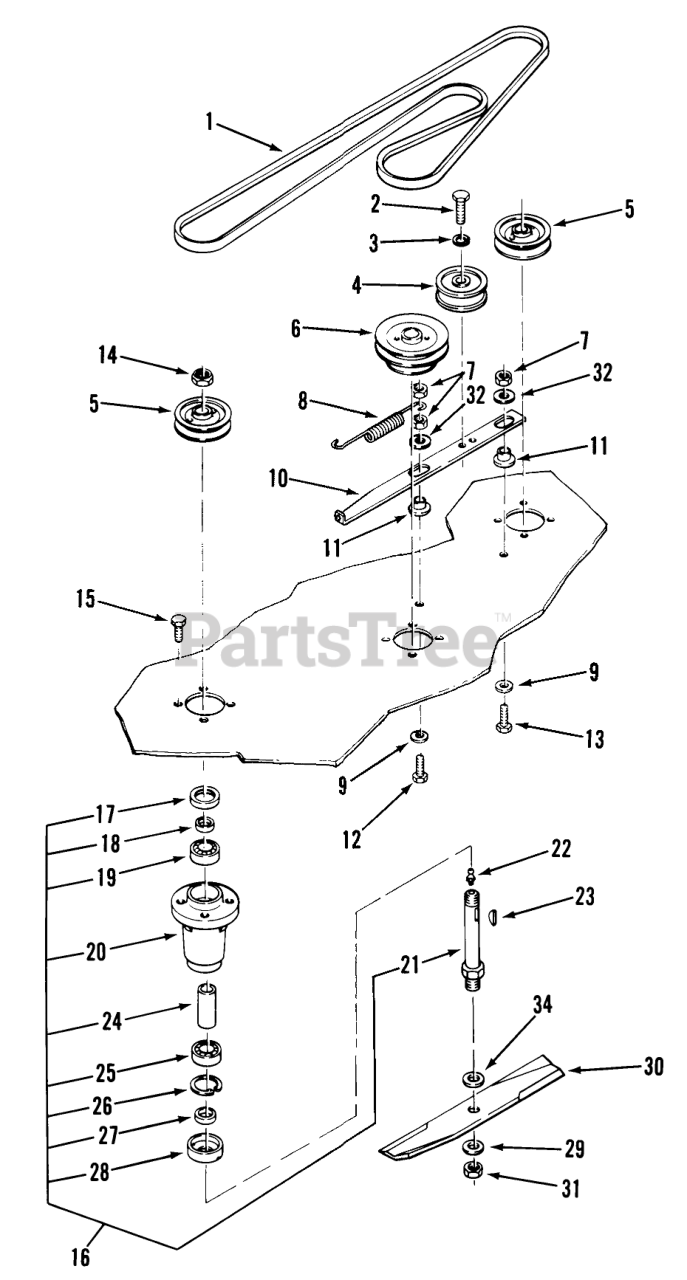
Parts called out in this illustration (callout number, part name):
1	V-BELT
1	V BELT
2	BOLT HEX SPECIAL
3	LOCKWASHER
4	Idler Pulley
5	PULLEY-BLADE DRIVE
6	PULLEY-48 MOWER SPDL
6	PULLEY-42 MOWER SPDL
7	NUT
8	SPRING-EXTENSION
9	WASHER
10	BAR-IDLER SUPPORT
11	SPACER-BUSHING
12	Bolt
13	Bolt
14	Nut
15	Bolt
16	Spindle Assembly
18	SPACER-SEAL
19	BEARING-BALL
20	HOUSING-SPINDLE
21	7" X 3/4" SHAFT.JAK
22	Zerk
23	Hi-Pro Key 3/16 x 5/8
24	SPACER
25	BEARING-BALL
26	Ring-Snap
27	SPACER-BLADE
28	CUP-SPINDLE
29	SpeciaI Washer
30	BLADE KIT (3 PACK)
30	14IN BLADE KIT
31	Nut
32	WASHER
34	Washer
